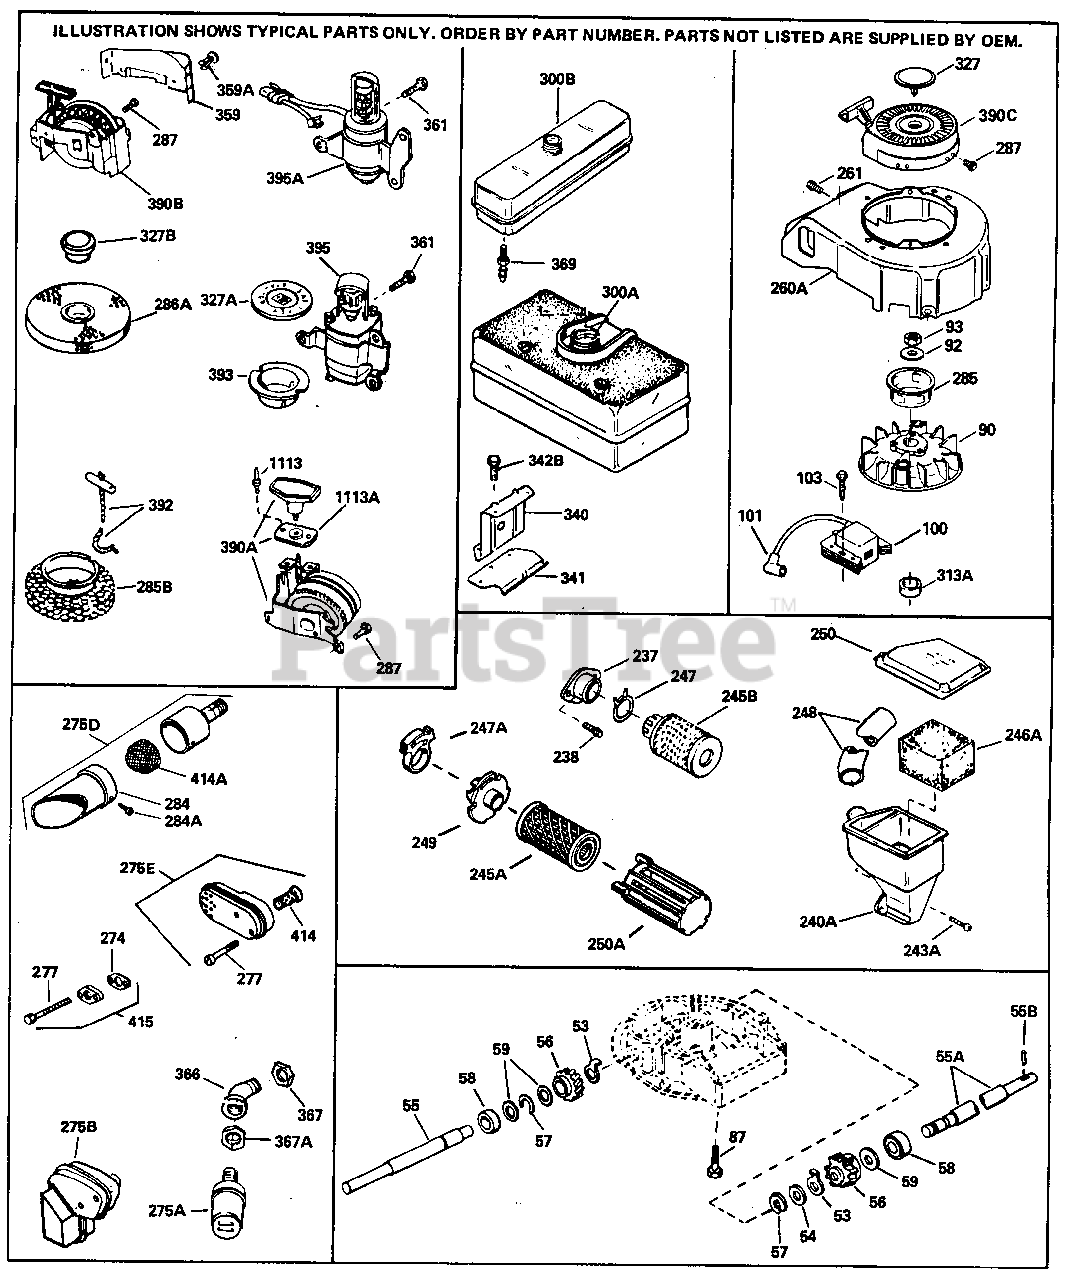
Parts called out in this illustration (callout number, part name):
92	Washer, Belleville
93	Nut, Flywheel
238	Screw, 10-32 x 1/2"
261	Screw, 1/4-20 x 5/8"
274	* Gasket, Exhaust (Use as required)
274	* Gasket, Exhaust
275D	Muffler (Incl. 284, 284A & 414A) (Thi s spark arrester mufflercan be used o n any model with a 3/4-14 tapped exha ust port.)
277	Screw, T-30, 1/4-20 x 1/2"
277	Screw, 1/4-20 x 2-3/8"
284	Cover & Tube, Muffler Use as require d
284A	Screw, 8-18 x 3/8" (Use as required)
285	Cup, Starter
287	Pop Rivet (Purchase locally) Use as r equired
414A	Screen, Muffler (Use as required)
415	Muffler Adapter Kit (Incl. 121 & 128) (Conventional Ports)
415	Muffler Adapter Kit (Incl. 274 & 277) NOTE: This muffler adapter can be us ed only on models which haveexhaust p ort on top (above intake). (Inverted Ports)
1113	Rivet, Open end (Can be purchased loc ally)
